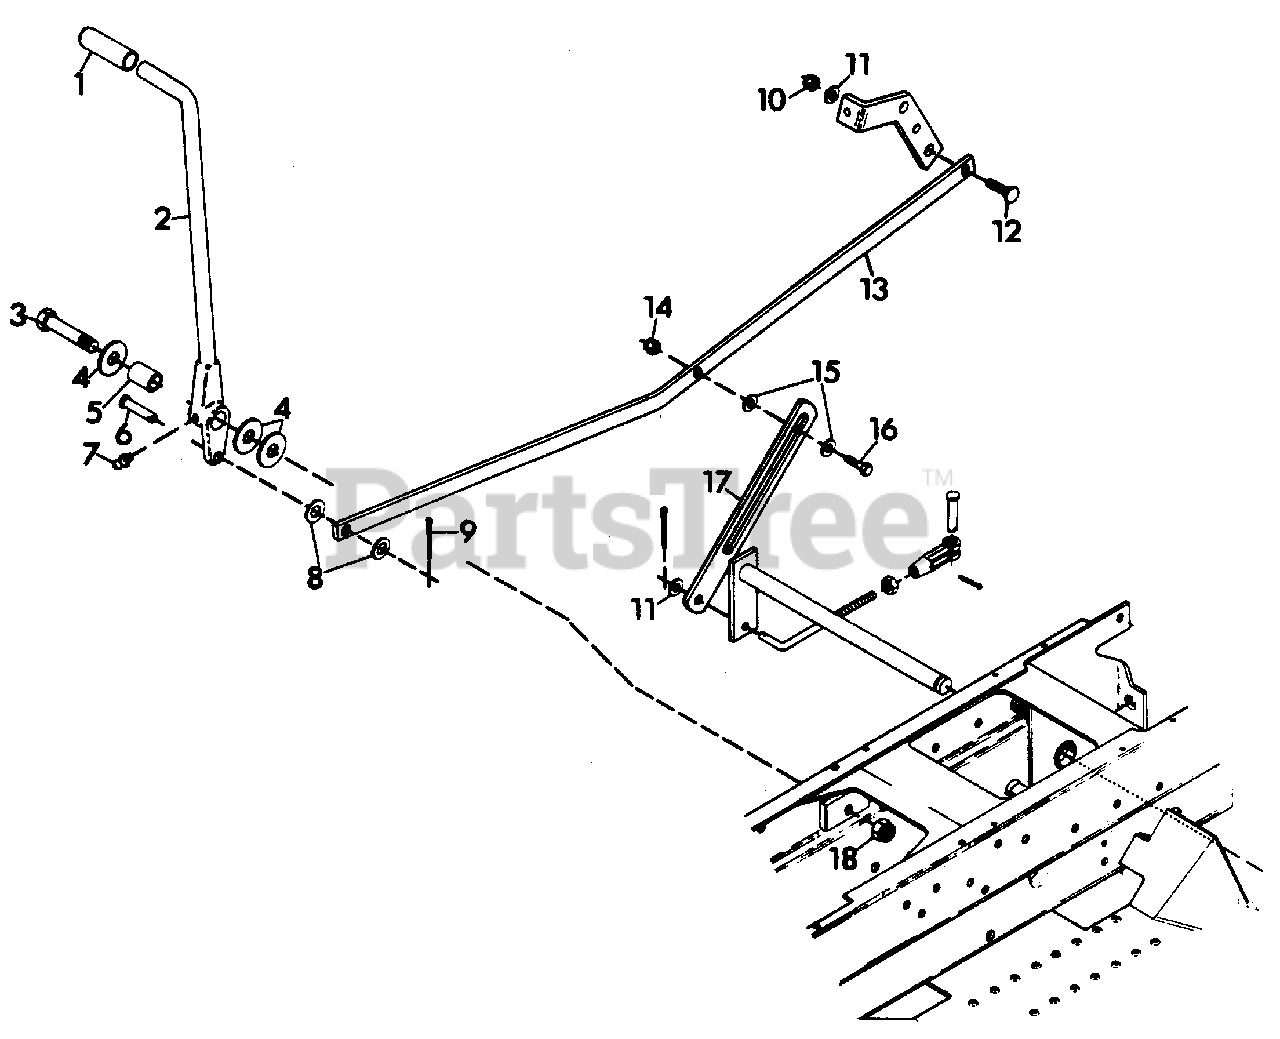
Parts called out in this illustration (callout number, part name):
1	Grip, Handle
2	Lever, Fwd-Rev
3	Bolt, Hex 1/2-13x2.75
4	Washer, Flat .563x1.375x.109
5	Bushing, .505x.74x1.438
6	Pin, Clevis .375x.948
7	Fitting, Lube 1/4-28
8	Washer, Flat .406x.812x.065
9	Pin, Cotter .09x.75
10	Nut, Lock 5/16-18
11	Washer, Flat .313x.875x.065
12	Bolt, 5/16-18x1.25 RdHdSqNk
13	Link, Fwd-Rev Shifter
14	Nut, Lock 1/4-20
15	Washer, Flat .281x.625x.065
16	Bolt, Hex 1/4-20x1.00
17	Strap, Neutral Return
18	Nut, Lock 1/2-13
